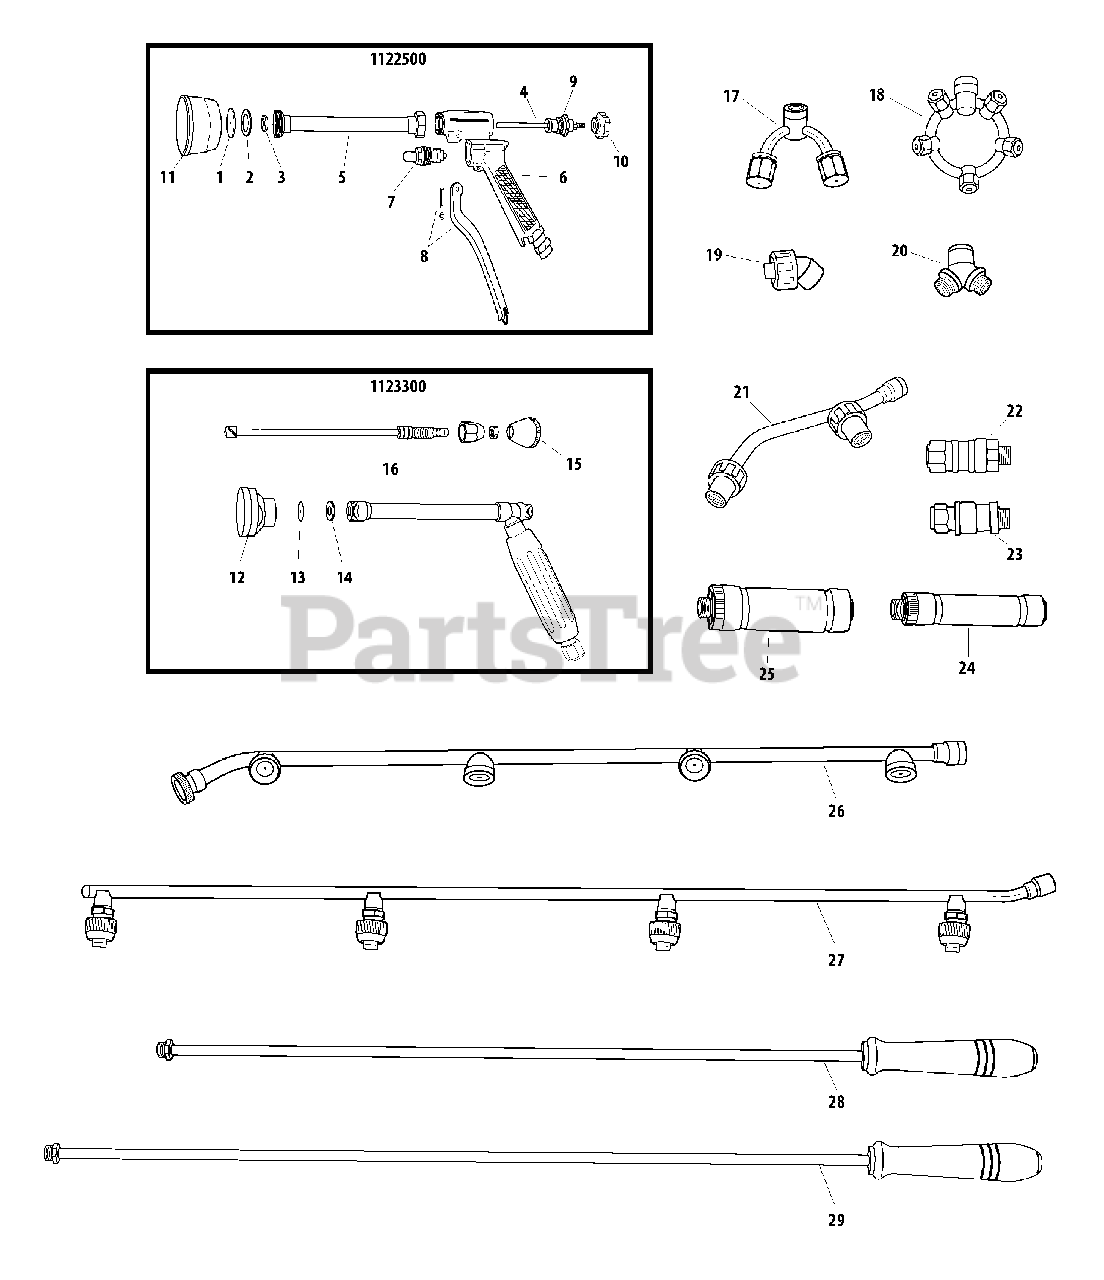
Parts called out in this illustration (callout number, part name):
1	PLATE, NOZZLE
2	O-RING
3	CORE, SWIRL
4	SHAFT ASSY, CENTER
5	PIPE
6	GRIP, SPRAY GUN
7	VALVE ASSY
8	TRIGGER ASSY
9	SEAL ASSY
11	CAP, NOZZLE
12	CAP, NOZZLE
13	PLATE, NOZZLE
14	O-RING
15	KNOB
16	SHAFT ASSY, CENTER
17	NOZZLE ASSY
18	NOZZLE ASSY
19	NOZZLE ASSY
20	ADAPTOR
21	NOZZLE ASSY
22	CONNECTOR, SWIVEL
23	SWIVEL
24	FILTER, FLUID
25	FILTER, FLUID - HEAVY DUTY
26	WAND ASSY, SPRAYER
27	WAND ASSY, SPRAYER
28	WAND, SPRAYER 680 MM
29	WAND, SPRAYER 890 MM
1122500	SPRAY GUN, PAL
1123300	GUN, SPRAY C2
